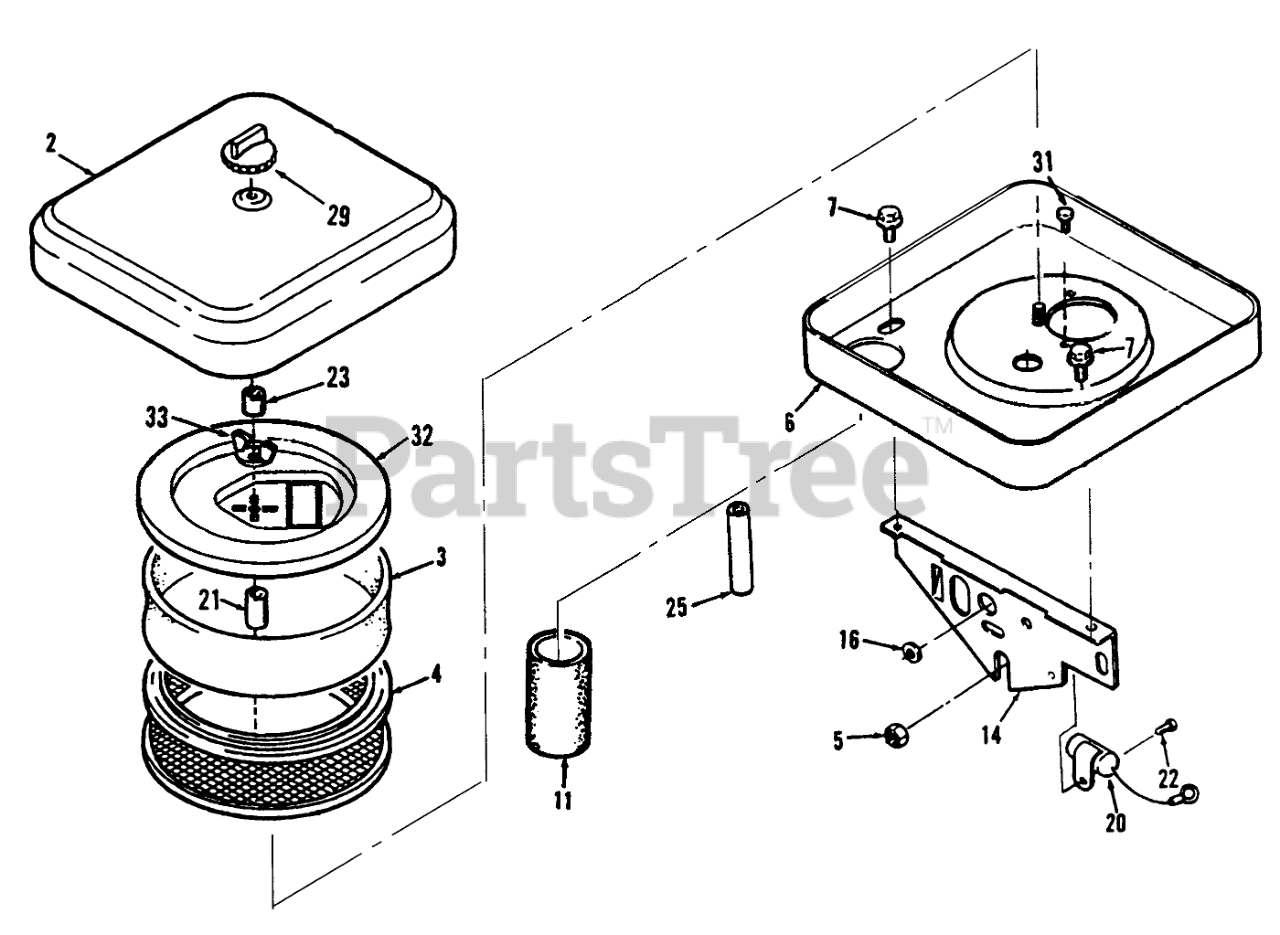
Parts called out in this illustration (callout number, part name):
2	AIR-CLEANER COVER
3	AIR CLEANER ELEMENT
4	Air Cleaner Element
6	AIR-CLEANER HOUSING
7	SCREW-TAPPING
11	AIR INTAKE TUBE
14	SUPPORT-AIR CLEANER
16	Grommet
20	CONDENSER
22	SCREW #10-32 X 5/8
23	SPACER-RUBBER
25	BREATHER TUBE
29	KNOB-TOOL LESS
31	MACHINE SCREW
32	Cover-Element
33	1/4-20 WING NUT
